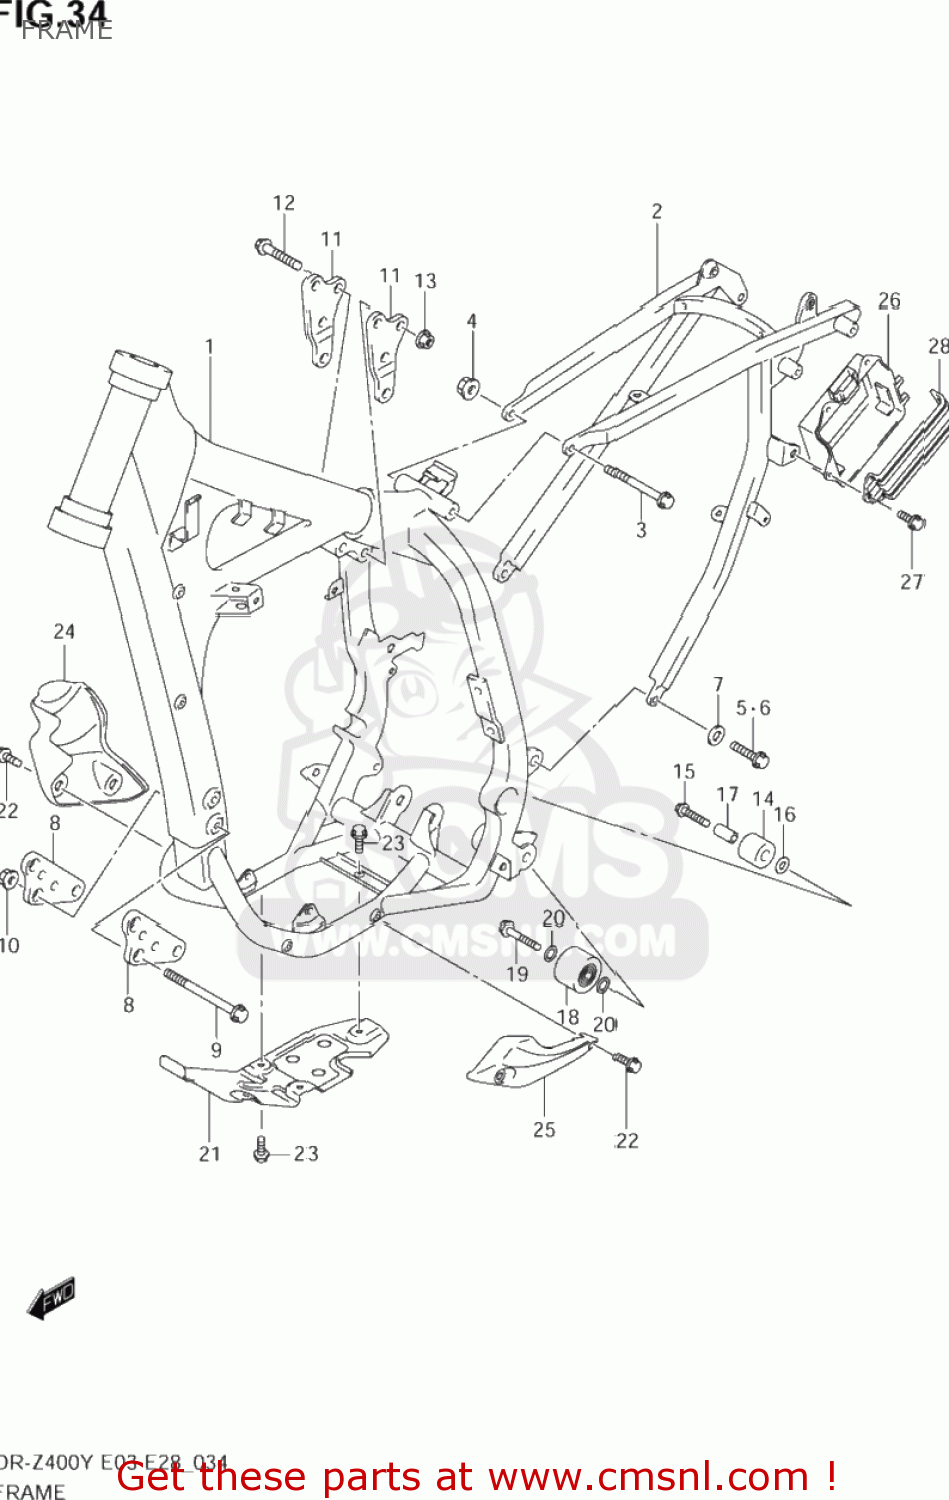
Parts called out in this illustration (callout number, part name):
1	FRAME COMP
2	RAIL COMP,SEAT
3	BOLT(8X115)
4	NUT
5	BOLT(8X18)
6	BOLT(8X20)
7	WASHER(8.5X18X2)
8	PLATE,ENG MTG FR
9	BOLT(8X90)
10	NUT
11	PLATE,HEAD MTG RR
12	BOLT(8X50)
13	NUT
14	ROLLER,CHAIN CONTROL UPR
15	BOLT(8X41)
16	WASHER
17	SPACER(8.6X12.2X26.5)
18	ROLLER,CHAIN
19	BOLT(8X41)
20	SHIM(8X12X1)
21	PROTECTOR,ENGINE
22	BOLT(8X16.5)
23	BOLT
24	GUARD,WATER PUMP
25	GUARD,MAG COVER
26	HOLDER,BATTERY
27	BOLT(6X17.8)
28	BAND,BATTERY HOLDER
